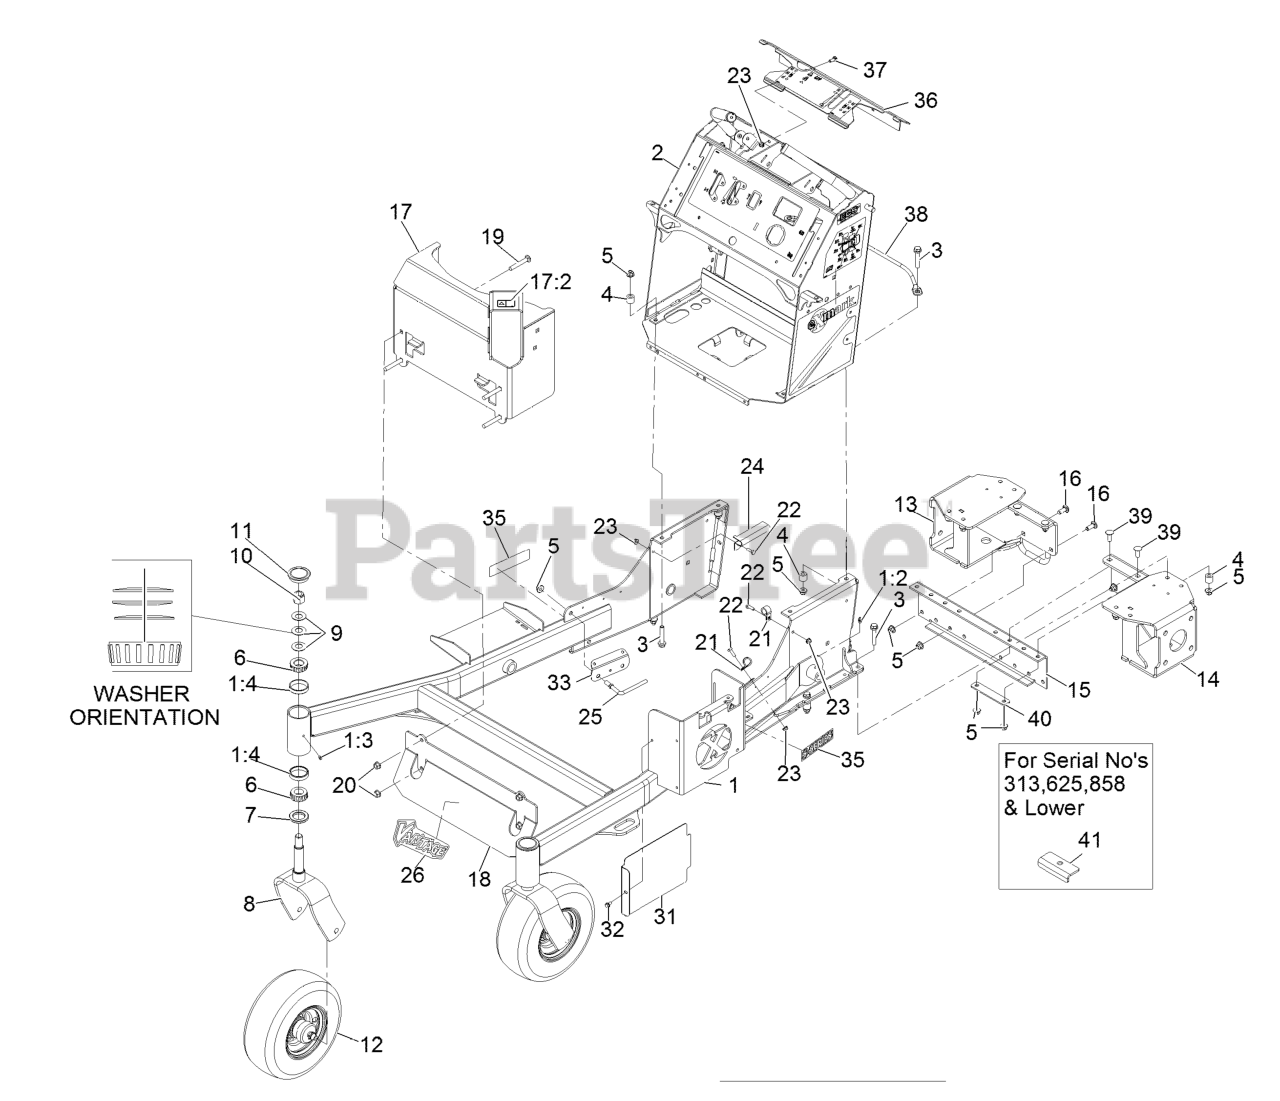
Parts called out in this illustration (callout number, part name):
1	FRONT FRAME ASM
1:2	FITTING-GREASE
1:4	CUP-BEARING
2	TOWER ASSEMBLY
3	SCREW-HHF
5	NUT-HF, NI
6	Cone-Bearing Tapered Roller
7	SEAL-GREASE
8	FORK-CASTER
9	WASHER-BELLVILLE
10	NUT-LOCK, NI
11	CAP-GREASE
12	WHEEL/TIRE AND BEARING AS
13	RH MOTOR MOUNT ASM
14	LH MOTOR MOUNT ASM
15	MOUNT-MOTOR, CENTER
16	SCREW-CARR
17:2	DECAL-WARNING
18	PANEL-GUARD
19	SCREW-CARR
21	CLAMP-CABLE
22	SCREW-HH
24	BRACKET-HOSE, FUEL
25	GUIDE-HOSE, SUPPORT
26	DECAL-VANTAGE LOGO
31	SHIELD-HEAT, TALL
32	SCREW-HWH
33	GUARD-HOSE
35	DECAL-X-SERIES
36	CONTROL PANEL W/DECALS
37	BOLT-CARR
38	ROD, GUARD
39	Bolt-Carriage 3/8-16 X 1 1/4
40	SPACER, UP STOP
41	Spacer-Up Stop
